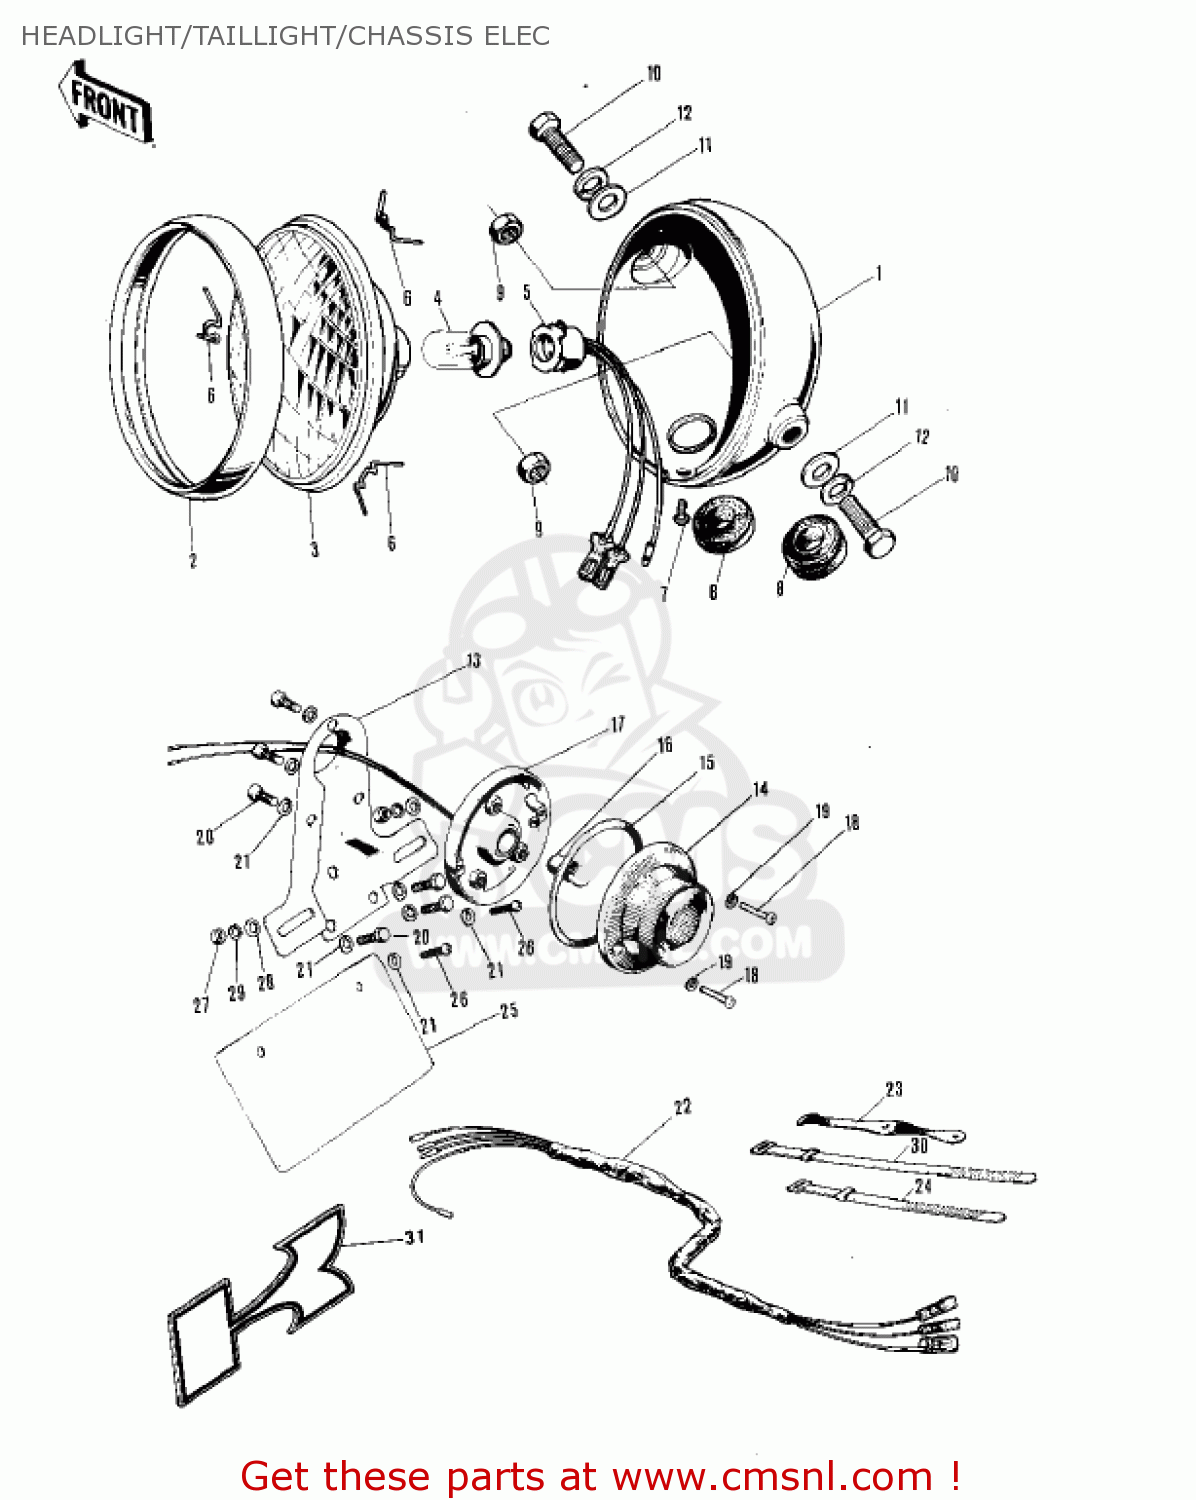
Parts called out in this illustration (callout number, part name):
1	BODY-COMP-HEAD LAMP,F
2	RIM,HEAD LAMP
3	LENS-COMP
4	BULB 6V 25/25W
5	SOCKET-ASSY,HEAD LAMP
6	SPRING,HEAD LAMP LENS
7	SCREW-OVL CNTSNK,5X8
8	GROMMET
9	NUT,10MM
10	BOLT-UPSET,10X20
11	WASHER-PLAIN,10MM
12	WASHER-SPRING,10MM
13	BKT-TAIL LAMP,BLACK
14	LENS,TAIL LAMP
15	GASKET-TAIL LAMP (NAS)
16	BULB 6V 10/3W
17	SOCKET-TAIL LAMP
18	SCREW-PAN HEAD,4X10
19	WASHER-SPRING,4MM
20	BOLT-UPSET
21	WASHER-SPRING,6MM
22	WIRING HARNESS-MAIN
23	BAND-RUBBER
24	BAND,SHORT
25	BRACKET-LICENSE PLATE
26	SCREW-PAN HEAD,6X12
27	NUT,6MM
28	WASHER-PLAIN-SMALL,6M
29	WASHER-SPRING,6MM
30	BAND,LONG
31	EMBLEM,LICENSE PLATE
?	LAMP-HEAD
